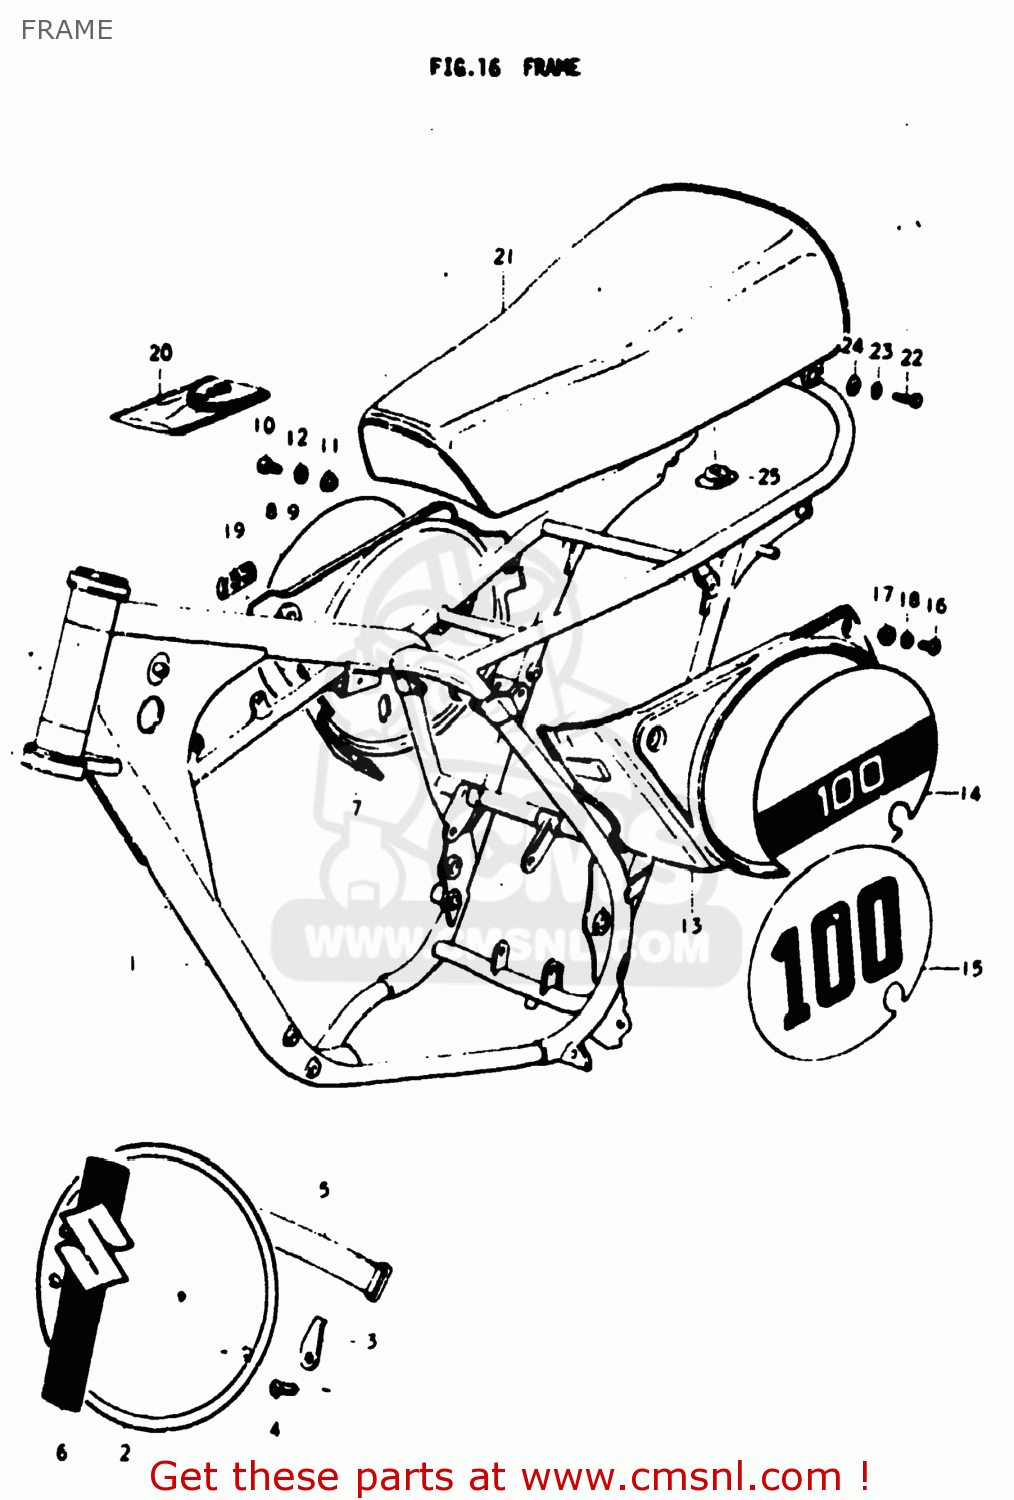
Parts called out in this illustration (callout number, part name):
1	FRAME
2	PLATE SET,FRONT
4	SCREW 6X12
5	BAND
6	EMBLEM,FRONT NUMBER PLATE
7	COVER,FRAME,RIGHT
8	EMBLEM
9	EMBLEM
10	SCREW 6X12
11	WASHER
12	LOCK WASHER
13	COVER,FRAME,LEFT
14	EMBLEM,FRAME COVER
15	EMBLEM,FRAME COVER
16	SCREW 6X12
17	WASHER
18	LOCK WASHER
19	EMBLEM,CCIS
21	SEAT ASSEMBLY
22	BOLT
23	LOCK WASHER
24	WASHER
25	CUSHION
